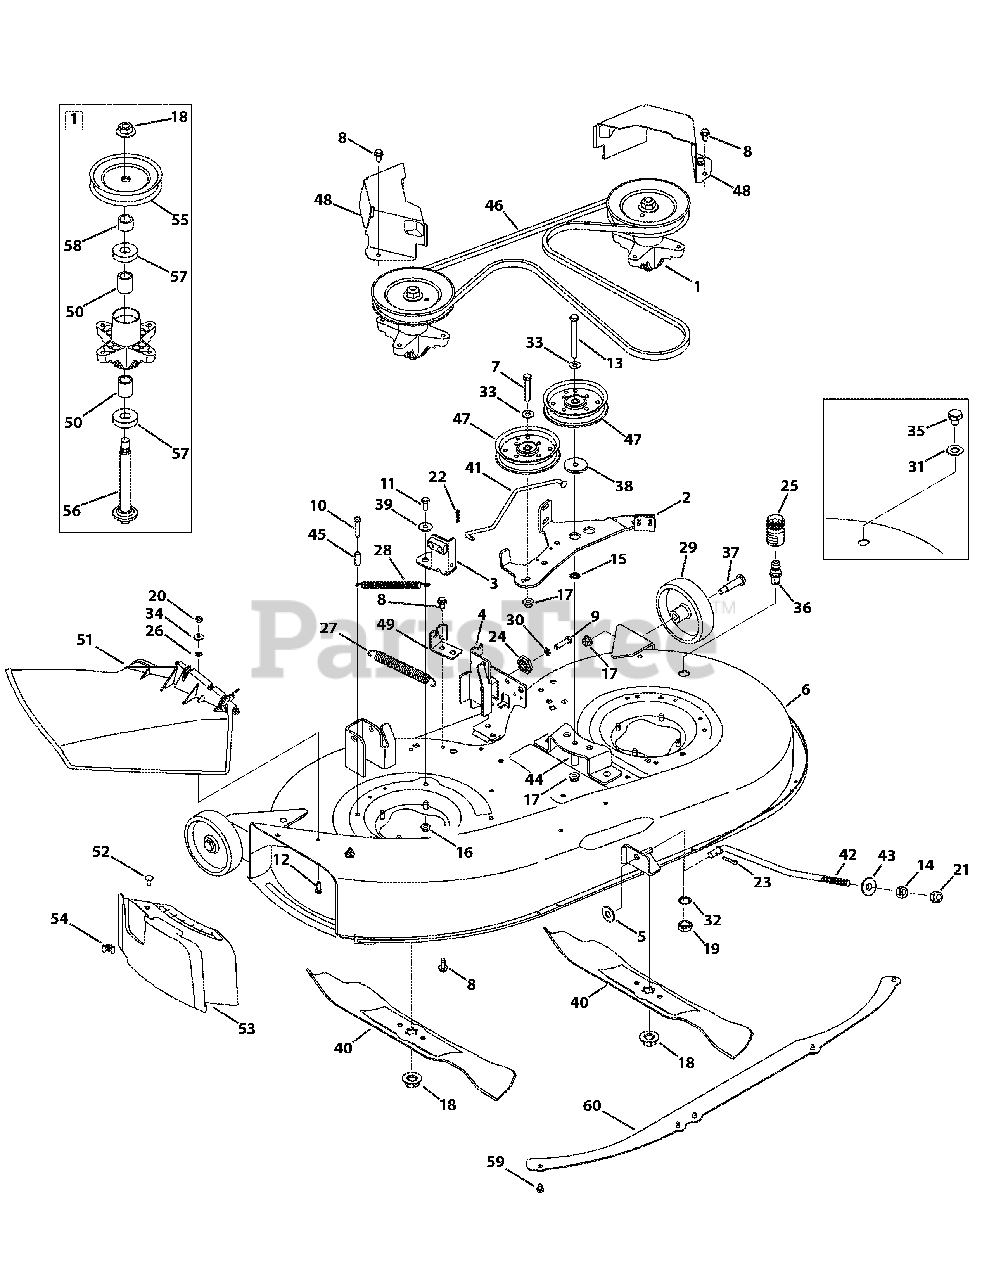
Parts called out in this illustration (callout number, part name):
1	Pulley Spindle Assembly, 6.3 DIA
2	Deck Brake Assembly
3	Deck Brake Assembly
4	Deck Hanger Bracket LH
5	Flat Washer, .531 x 1.25 x .100
6	Deck Assembly, 42" w/ Wheel
6	Deck Assembly, 42" w/o Wheel - Black
6	Deck Assembly, 42" w/o Wheel - Green
6	Deck Assembly, 42" w/o Wheel - Red
7	Hex Screw, 3/8-16 x 1.75
8	Screw, 5/16-18 x .750
9	Hex Screw, 5/16-18 x 1.25
10	Screw, 1/4-20 x 1.500
11	Hex Screw, 5/16-18 x .75
12	Hex Screw, 1/4-20 x .75
13	Hex Screw, 3/8-16 x 3.50
14	Hex Nut, 1/2-13:GR5
15	Push Nut, 3/8
16	Flangelock Nut, 5/16-18
17	Flangelock Nut, 3/8-16
18	Flange Nut, 5/8-18
19	Hex Nut, M16-1.5
20	Hex Nut, 1/4-20
21	Hex Locknut, 1/2-13
22	Cotter Pin, .072 DIA. x 1.13 LG
23	Cotter Pin, 3/16 x 1.00
24	Deck Gear Adjuster
25	Water Nozzle Adaptor
26	Push Nut, .25 ID X .50 OD
27	Extension Spring, 0.75 OD x 6.375
28	Extension Spring, .500 DIA x 6.375
29	Deck Wheel, 5.0 x 1.38
30	Lock Washer, 5/16
31	Flat Washer, 1/2 x 1.25 x .10
32	Lock Washer, 5/8
33	Flat Washer, .385 x .87 x .06
33	Flat Washer, .406 x .875 x .059
34	Bell Washer, .265 X.75 x .062
35	Bolt Plug, M16 x 1.5
36	Water Nozzle
37	Shoulder Bolt. .496 x 1.525:3/8-16
38	Shoulder Spacer, .8840 x .190
39	Shoulder Spacer, .5000 x .1475
40	3 in 1 Blade
41	Brake Control Rod
42	Deck Lift Rod
43	Deck Lift Pivot
44	Spacer, 3/8 ID x .68 OD x 1.46 LG
45	Spacer, .260 x .375 x 1.030 LG
46	V-Type Belt
47	Idler Pulley
48	Belt Cover - Powder Black
48	Belt Cover - Red
48	Belt Cover - Green
48	Belt Cover - Black Jack
49	Deck Engage Cable Bracket
50	Spacer, .80 x 1.10 x 1.322
51	Chute Assembly
52	Carriage Screw, 1/4-20 x .62
53	Mulch Plug
54	Wing Nut, 1/4-20
55	Deck Pulley, 6.3 Diameter
56	Spindle Shaft, 5.50 LG
57	Ball Bearing, .787ID x 1.85OD x .551
58	Spacer, .820 x 1.150 x .480
59	Screw, 1/4-20 x .500
60	42" Deck Skirt
